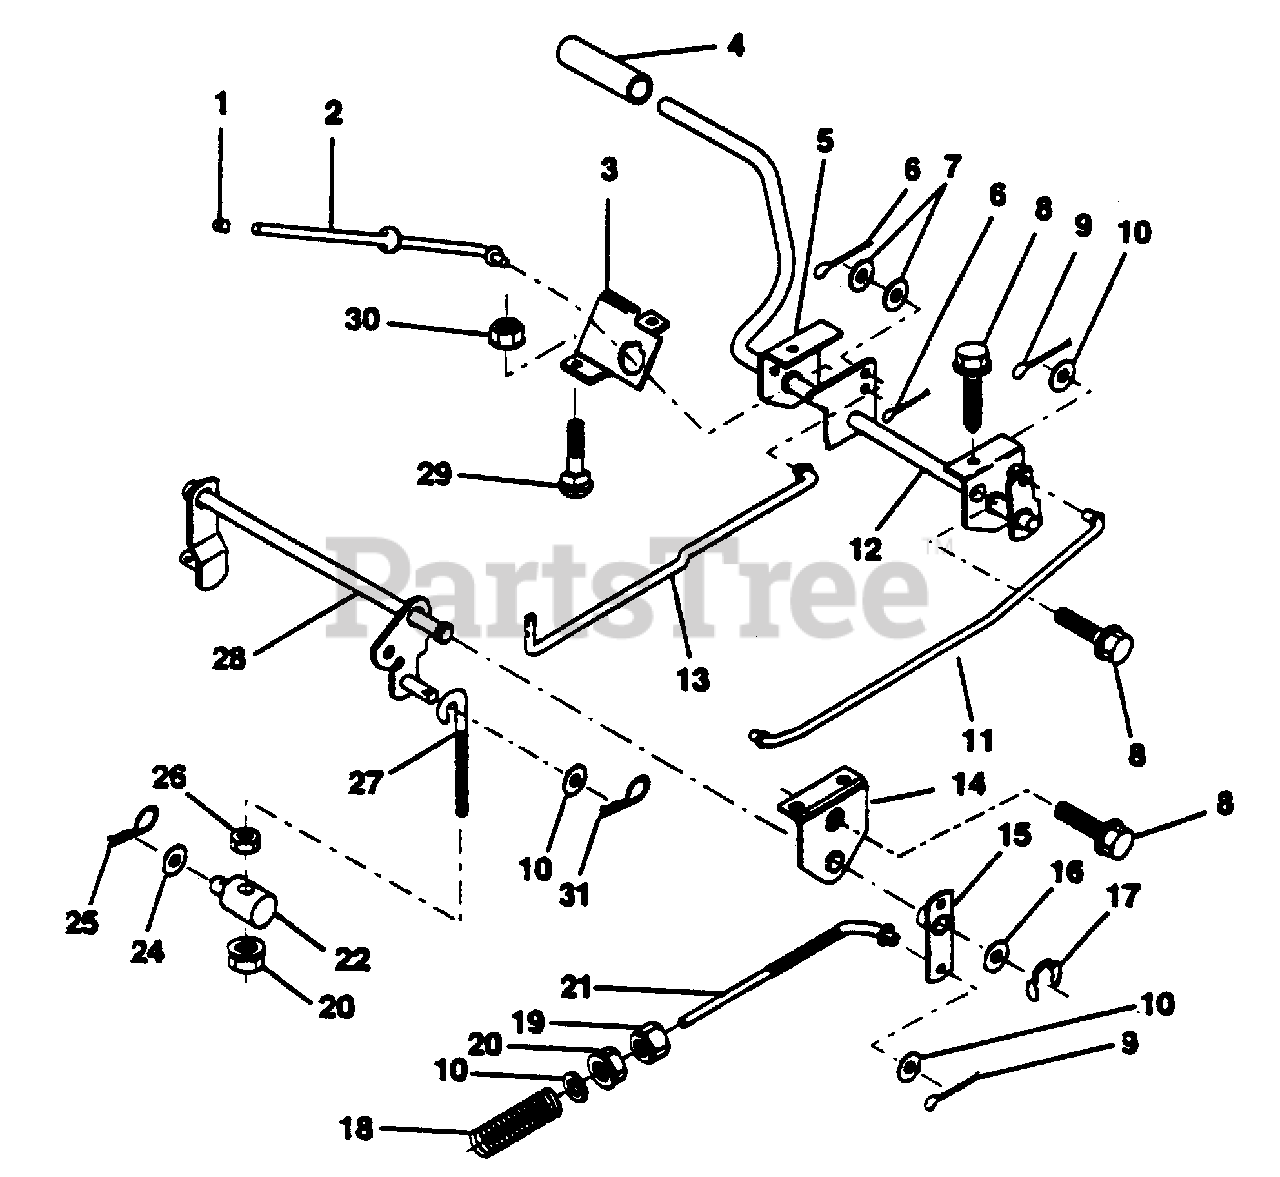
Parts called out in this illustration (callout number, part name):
1	Cap, Plunger (AYP part number)
2	Rod, Parking Brake (AYP part number)
3	Bracket, Parking Brake (AYP part number)
4	Cover, Pedal (AYP part number)
5	Bracket, Clutch/Brake Pedal, L.H. (AYP part number)
6	Pin, Cotter 3/32 x 3/4 (AYP part number)
7	Washer 13/32 x 5/8 x 16 Ga. (AYP part number)
8	Screw, Hex, Thd. Roll. 5/16-18 x 1/2 (AYP part number)
9	Pin, Cotter 1/8 x 3/4 (AYP part number)
10	Washer 13/32 x 13/16 x 16 Ga. (AYP part number)
11	Rod, Brake Front (AYP part number)
12	Assembly, Clutch/Brake Pedal (AYP part number)
13	Rod, Clutch (AYP part number)
14	Bracket, Lift, Shaft (AYP part number)
15	Assembly, Brake, Pivot, Arm (AYP part number)
16	Washer 25/32 x 1-1/8 x 16 Ga. (AYP part number)
17	Ring, Klip (AYP part number)
18	Spring, Brake Rod (AYP part number)
19	Nut, Hex, Jam 3/8-16 UNC (AYP part number)
20	Nut, Crownlock 3/8-16 UNC
21	Rod, Rear Brake
22	Trunnion, Lift (AYP part number)
23	Nut, Crownlock 3/8-16
24	Washer 13/32 x 1-1/4 x 12 Ga. (AYP part number)
25	Spring, Retainer (AYP part number)
26	Nut, Centerlock 3/8-16 UNC (AYP part number)
27	Link, Threaded (AYP part number)
28	Assembly, Rear Mower Lift (AYP part number)
29	Bolt, Carriage 5/16-18 UNC x 3/4 (AYP part number)
30	Nut, Keps 5/16-16 UNC (AYP part number)
